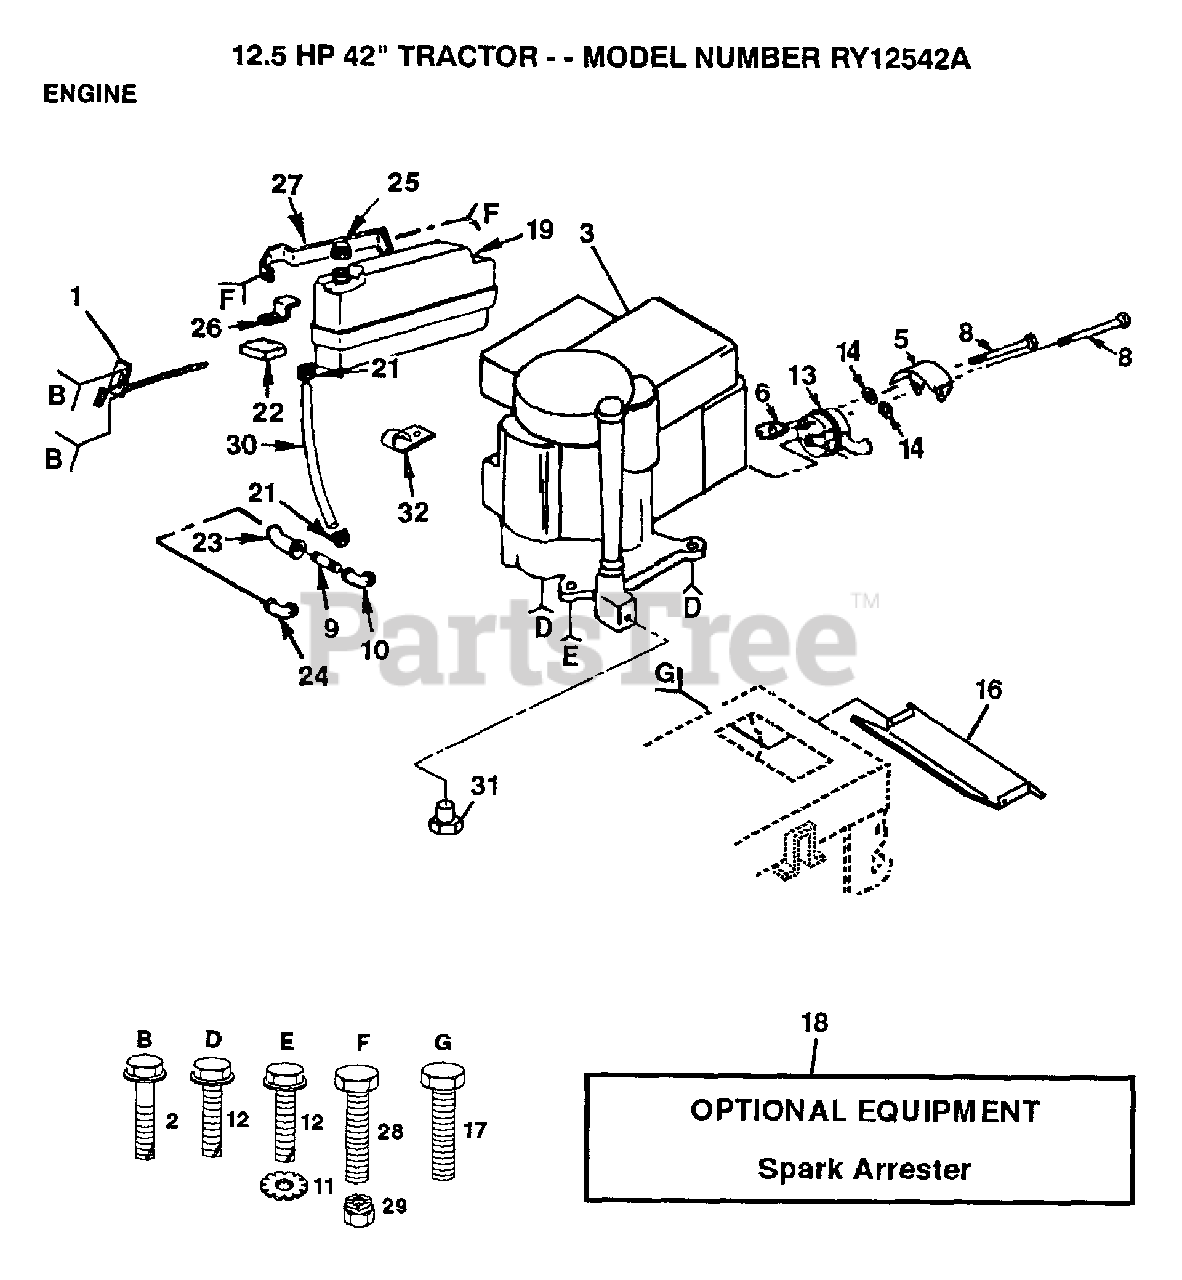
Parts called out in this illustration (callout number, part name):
2	SCREW LT
5	HEAT SHIELD
8	BOLT
9	PIPE NIPPLE
10	STREET ELBOW LT
11	LOCKWASHER
12	SCREW
13	MUFFLER
17	SCREW
19	FUEL TANK
21	HOSE CLAMP
22	PAD-SPACER T
23	STREET ELBOW LT
24	ELBOW
26	BRACE-TANK LT
27	SUPT TANK FUEL
28	BOLT
29	NUT CROWN LOCK
30	HOSE T
32	CLIP T
